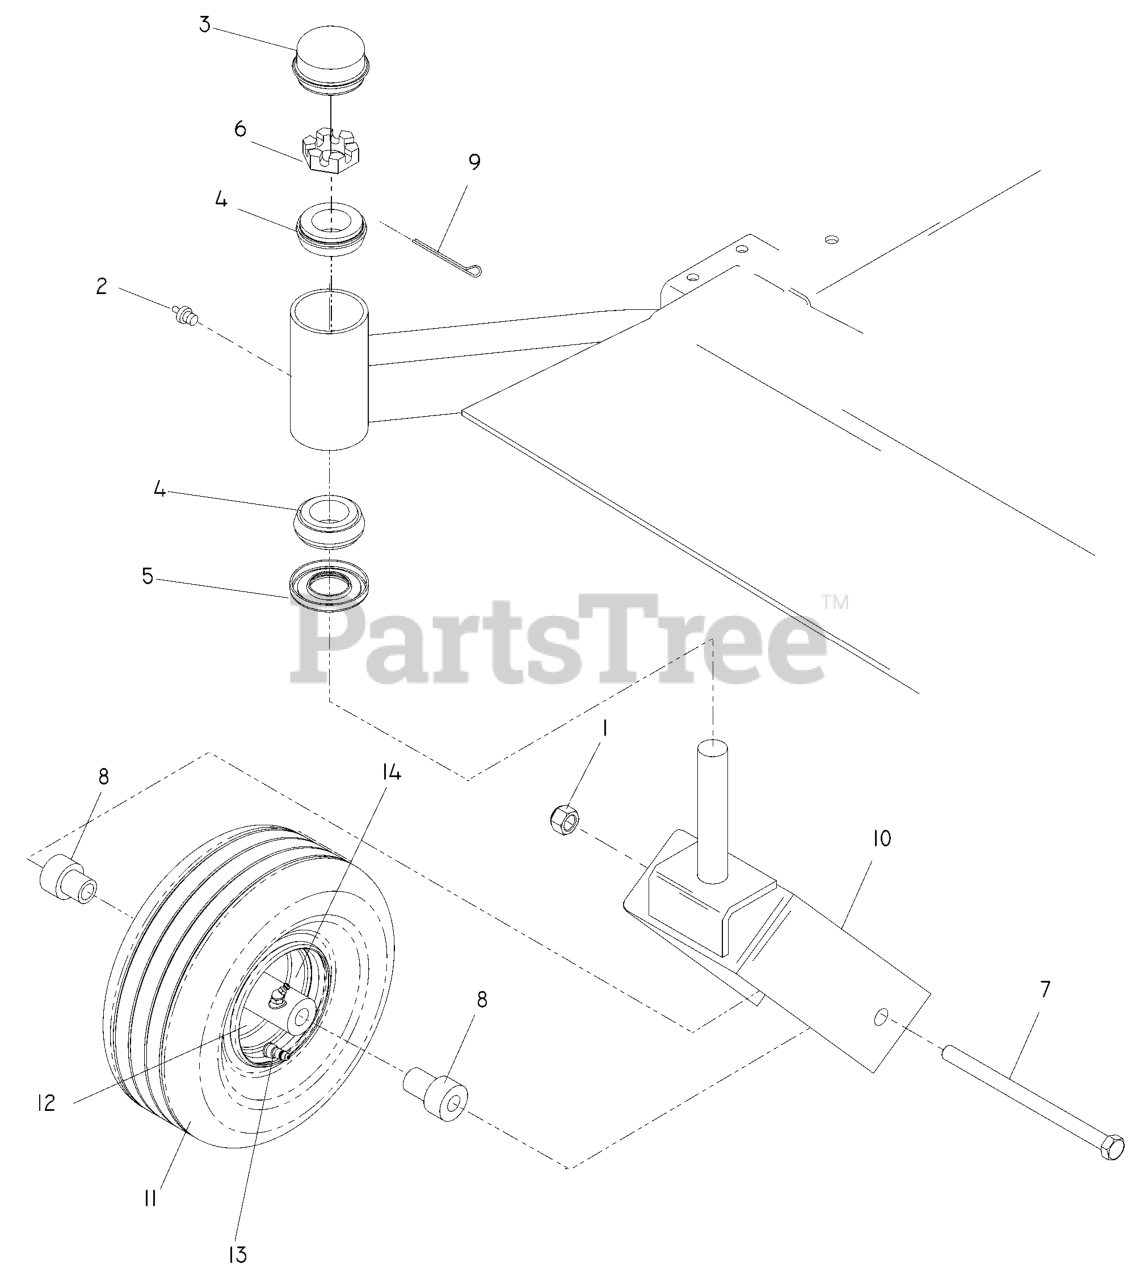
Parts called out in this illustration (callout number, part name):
1	NUT 1/2-13 HEX NYLOC ZD
2	ZERK
3	GREASE CAP
4	TAPERED ROLLER BRG
6	NUT 1"C HEX SLOTTED
7	HEX SCREW 1/2-13 X 9.5 GR5
8	AXLE SPACER
9	COTTER PIN 1/8 X 2
10	CASTOR YOKE ORANGE
11	FRONT TIRE ASSY
13	VALVE STEM TR-412
14	ZERK
